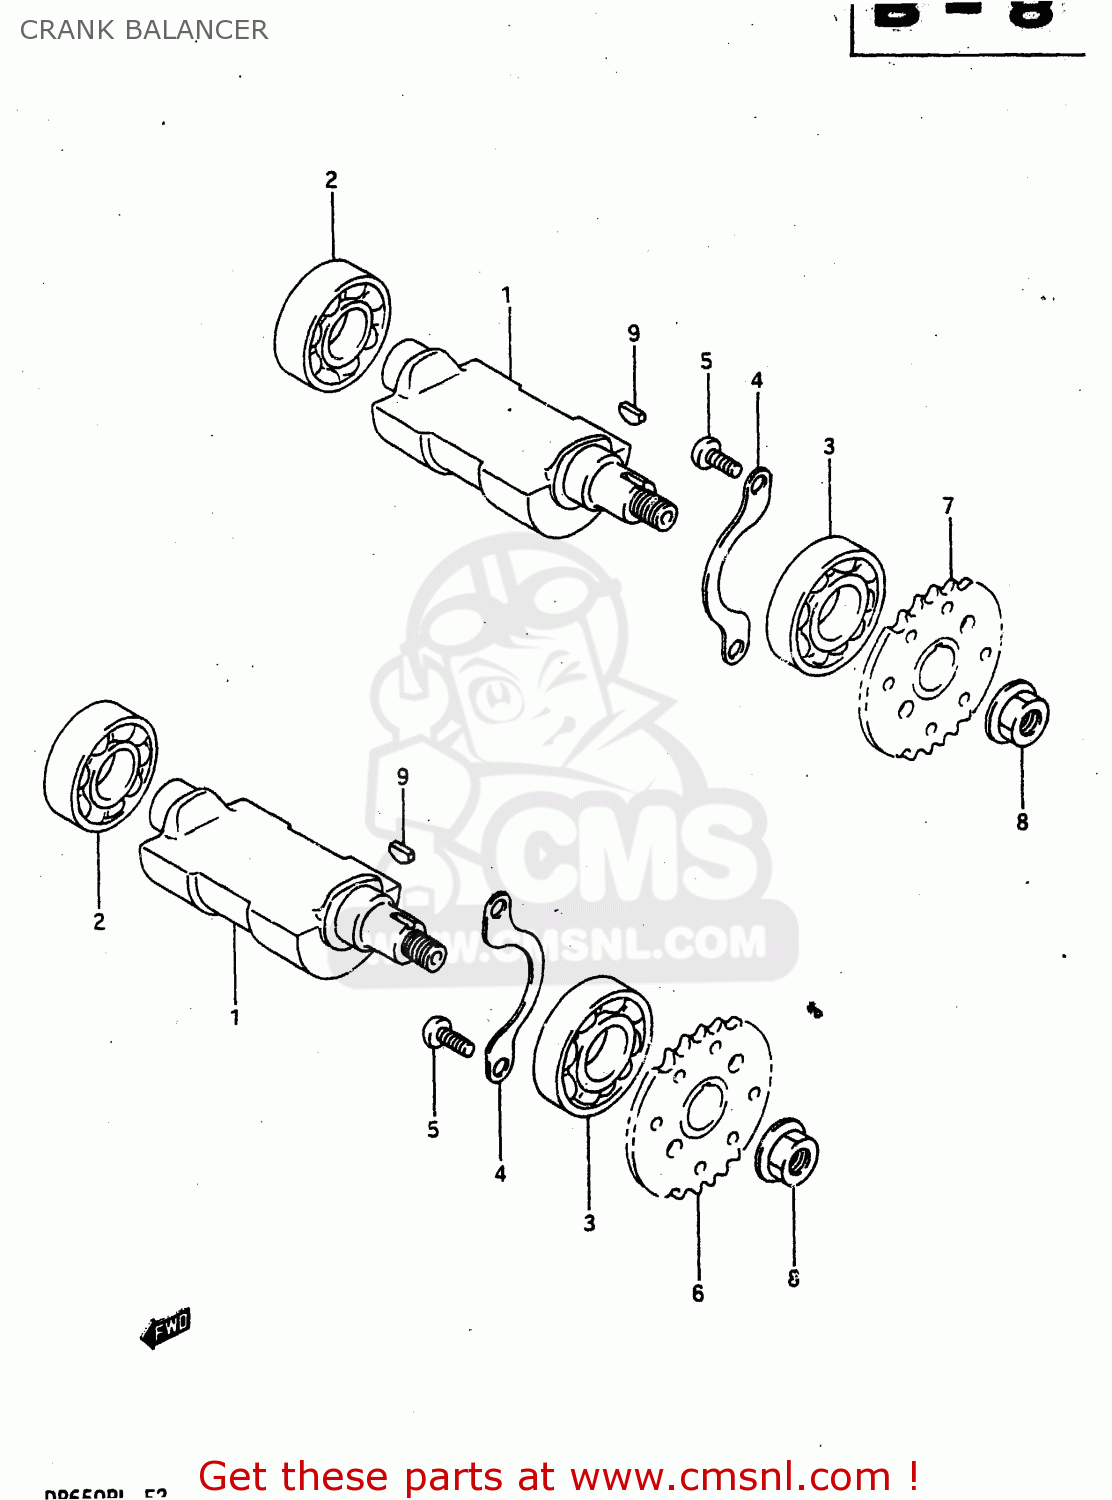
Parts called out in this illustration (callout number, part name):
1	BALANCER,CRANKSHAFT
2	BEARING(20X42X12)
3	BEARING(20X47X12)
4	RETAINER,CRANK BAL BEARING
5	SCREW
6	SPROCKET,BALANCER DRIVE
7	SPROCKET,BALANCER DRIVEN RR
8	NUT
9	KEY
